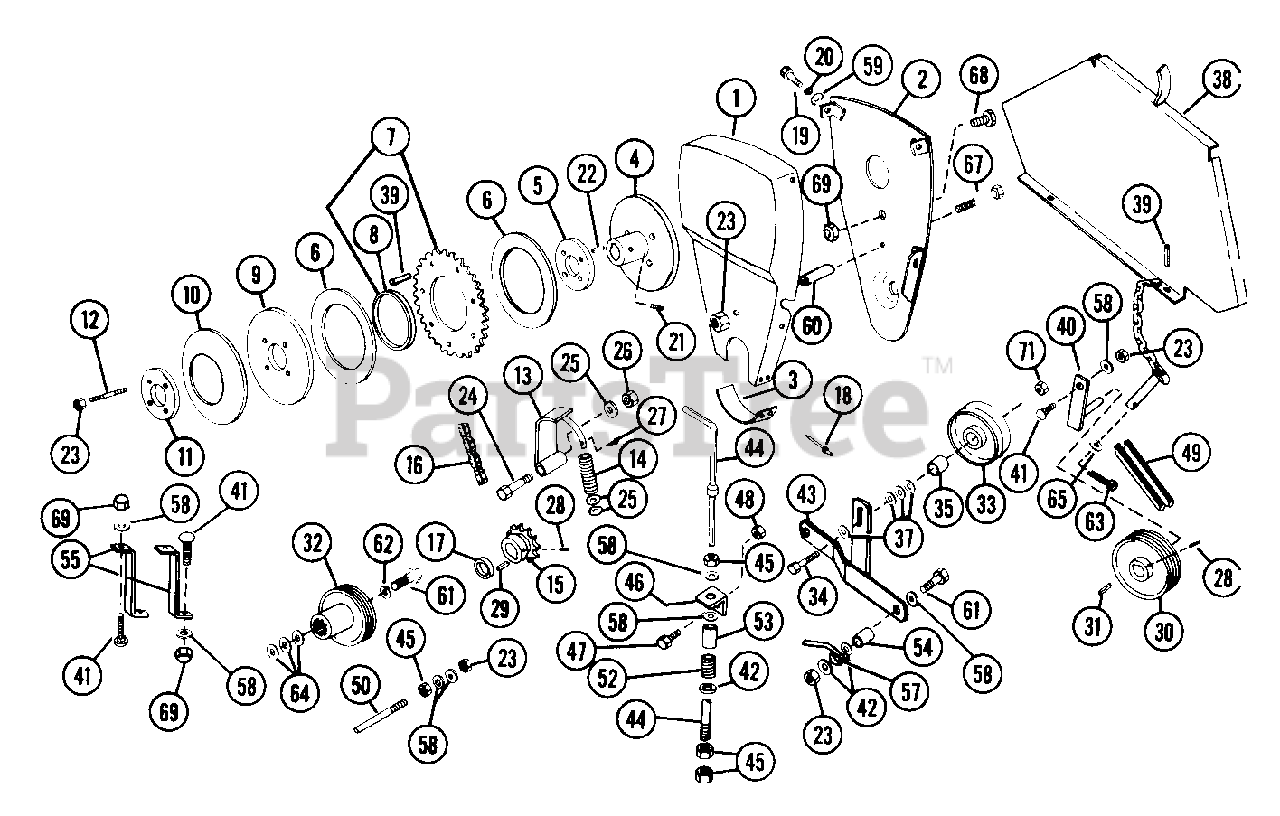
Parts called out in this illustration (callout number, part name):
1	CHAIN GUARD
2	CHAIN GUARD
4	SPROCKET & HUB
6	CLUTCH DISC
7	SPROCKET ASSEMBLY
8	BSHG-SLV 3.000X3.50X.50X3.506
9	OUTER DISC
10	BELLIEVILLE WASHER
13	CHAIN TIGHTNER
14	SG-COMP .075X.22X2.38
15	SPROCKET
16	AUGER DRIVE CHAIN
17	SPACER .760X1.000X.187
18	RVT-POP.187X.277 DOME ST
19	BLT-HEX .31-18X.50 GR5
20	WSHR-LK .312X.097 PL HVY
21	SET SCREW
22	KEY-STR .25X1.75X.25
23	NUT-LK .375-16 PL
24	BLT-HEX .31-18X2.25 PL GR5
25	WSHR-FL-STL.344X.688X.065PL
26	NUT-LK .312-18 GR A PL
27	PIN-COTR .12X.75 PL
28	SCR-SET .32-18X.50 SKH
29	KEY-SQ .188X1.0X.188 SAE 8630
31	KEY-SQ .188X1.5X.187 SAE 8630
32	REAR PTO KIT
33	IDLER-FLAT 4.0 X .50
34	BLT-HEX .50-13X2.50 PL GR5
35	SPACER .510X.750X.750
37	WSHR-FL-STL .531X1.062X.095 PL
38	BELT SHIELD
39	PIN-ROLL .313X.75
40	BELT GUIDE
41	BLT-RDHDSQNK .38-16X1.0 GR5PL
42	WSHR-FL-STL .390X.750X.125 PL
43	IDLER ARM
44	CLUTCH ROD
45	NUT-HEX .375-16
47	BLT-HEX .25-20X.75 PL GR5
48	NUT-LK TOP .250-20 PL
49	V-BELT, HA-WRAPPED (SET)
52	SG-COMP .090X.75X1.125
53	SPACER .384X.500X1.500
54	SPACER .384X.502X.840
55	BRACKET
57	BELT GUIDE
58	WSHR-FL-STL .438X1.0X.083 PL
59	WSHR-FL-STL .38X.875X.083 PL
60	SPACER .423X.675X2.125
61	BLT-HEX .38-16X2.25 GR2
62	WSHR-LK .375X.115 HVY PL
63	PIN-COTR .18X1.50 PL
64	SPACER-SPECIAL CONICAL
65	WSHR-FL-STL .755X1.375X.125 PL
67	BLT-HEX .38-16X2.75 PL GR5
68	SCR-MCH .31-18X1.00 SLFL PL
69	NUT-CROWN .312-18 PL
71	NUT-LK-CTR .50-13
